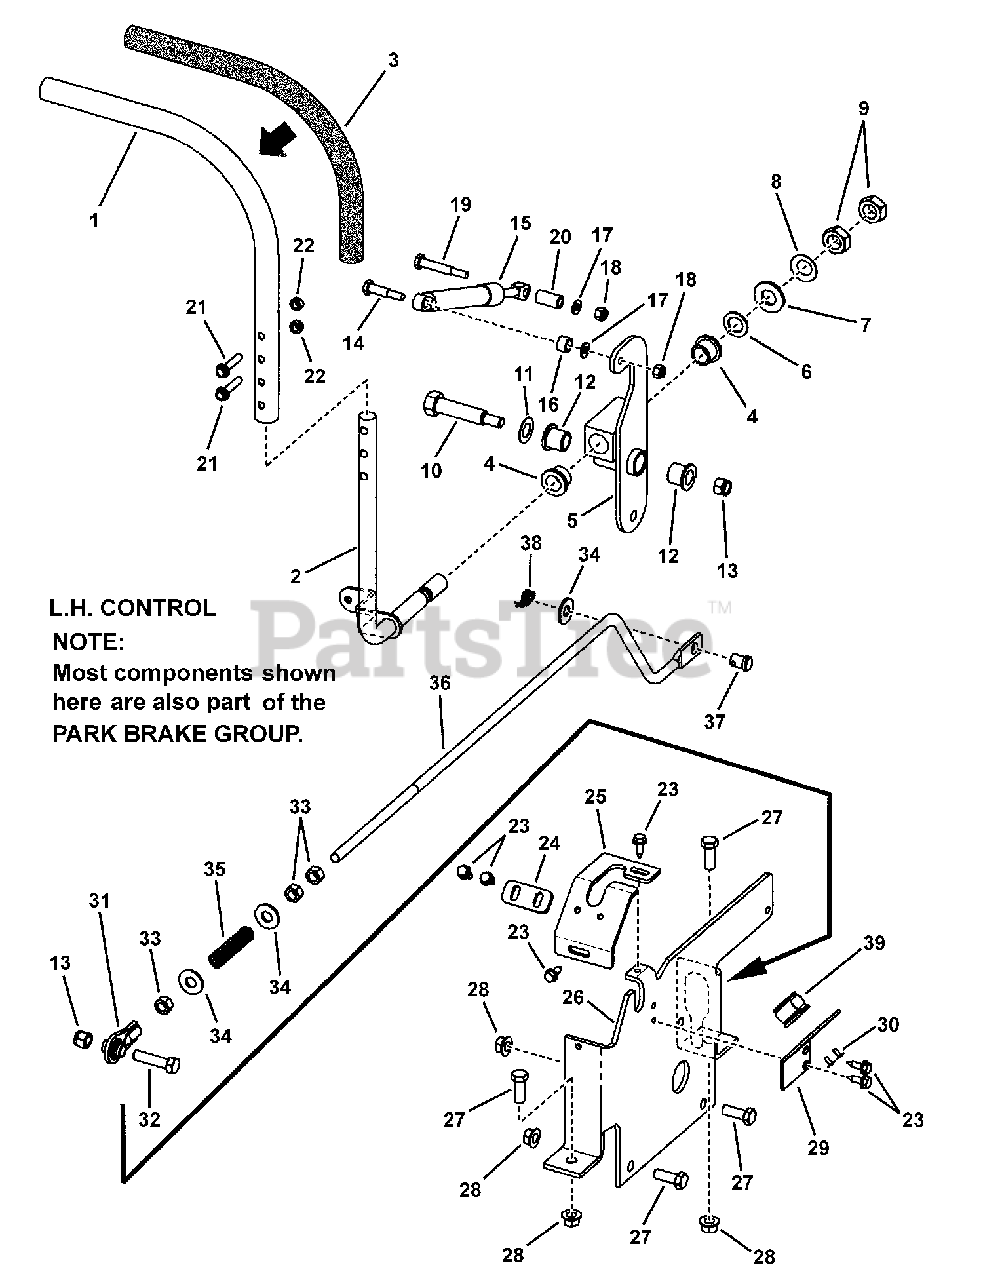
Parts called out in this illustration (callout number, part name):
1	HANDLE
2	WELD, Control Arm, LH, Yellow
3	GRIP, Handle
4	BUSHING, ST, Powdered Metal
5	WELD, Control Bracket, LH, Yellow
6	WASHER, Nylon, 5/8 ID.X1"OD.X.065
7	WASHER, .668X1.324X.098 YZ
8	WASHER, Bellville, .64X1.125X.028
9	NUT, Hex, Jam, 5/8F ZP
10	SHOULDER BOLT, 3/8C
11	WASHER, Thrust, .562 X 1.000 X .031
12	BEARING, Flange, 9/16
13	NUT, Hex, 3/8C, Nylock YZ
14	SHOULDER BOLT, 5/16 X 1/4C
15	DAMPENER
16	SPACER, .33 X .50 X .355, Yellow
17	WASHER, 1/4" ID, Harden
18	NUT, Hex Lock Nylon, 1/4C YZ
19	SHOULDER BOLT, 5/16 X 1/4C
20	SPACER, .33 X .50 X .929, Yellow
21	CAPSCREW, Hex Head, 1/4C X1-1/4" GR5 YZ
22	NUT, Hex Center Lock, 1/4C YZ
23	CAPSCREW, Hex Head Flange Taptite, 1/4C X3/4 BZ
24	PLATE, Fwd/Rev Adjust
25	TRACK, Control Stick, LH
26	BRACKET, Control, LH
27	CAPSCREW, Hex Head, 3/8C X1 GR5 YZ
28	NUT, Hex Flange Lock, 3/8C YZ
29	BRACKET, Rod Holder, RZT
30	POP RIVET, 1/8X3/8
32	CAPSCREW, Hex Head, 3/8C X1-1/2 GR5 YZ
33	NUT, Hex, 3/8F GR5 YZ
34	WASHER, .438X1X.084 YZ
35	SPRING, Brake Compression
36	ROD, Link Fwd/Rev
37	CLEVIS PIN, 7/16 X 1
38	PIN, Cotter, 1/2 Self, YZ
39	CLIP, Spring
